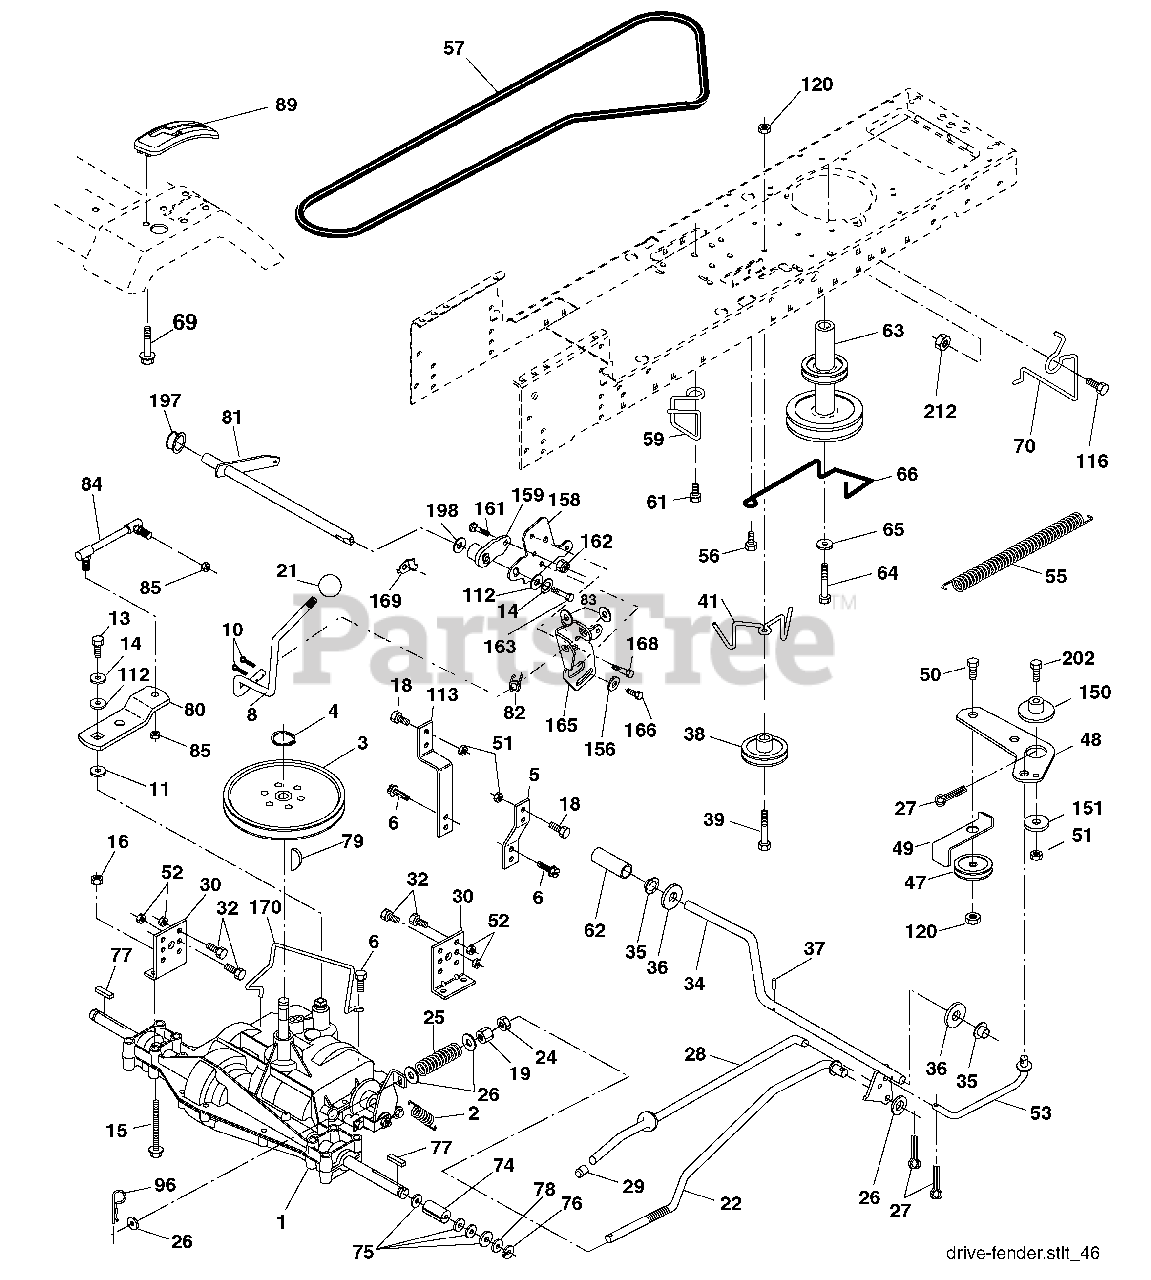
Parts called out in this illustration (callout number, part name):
2	Spring Return Brake T/a Zinc
3	Pulley Transaxle 18" tires
4	Ring Retainer # 5100-62
5	Strap Torque 30 Degrees
6	Screw 5/16-18 x 3/4
8	Rod Shift Fender Adjust Lt
10	Pin Cotter 1/8 x 1 Cad
11	Washer Plate Shf 388 Sq Hole
13	Bolt 1/4-28 unf Gr. 8 W/Patch
14	Washer Lock Hvy Helical
15	Bolt Hex FLGHD 5/16-18 Gr. 5
16	Nut Lock Hex w/ins 5/16-18
18	Bolt, Fin Hex 3/8-16 unc x 1 Gr. 5
19	Nut Lock 3/8-16 unc
21	Knob
22	Rod Brake Blk Zinc 26 840
24	Nut Hex Jam 3/8-16 unc
25	Spring Rod Brake 2 00 Zinc
26	Washer 13/32 x 13/16 x 16 Ga.
27	Pin Cotter 1/8 x 3/4 Cad
28	Rod Brake Parking LT/YT
29	Cap Brake Parking
30	Bracket Mtg Transaxle
32	Bolt Hex Hd 5/16-18 unc x 3/4
34	Shaft Asm Pedal Foot
35	Bearing Nylon Blk 629 Id
36	Washer 21/32 x 1 x 16 Ga.
37	Pin Roll 3/16 x 1"
38	Pulley Composite Flat
39	Bolt RDHD 3/8-16 unc x 2-3/4 Gr.
41	Keeper Belt Flat Idler
47	Pulley Idler V Groove Plastic
48	Bellcrank Asm
49	Retainer Belt Style Spring
50	Bolt Carr. Sh. 3/8-16 x 1-1/2 Gr. 5
51	Nut Crownlock 3/8-16 unc
52	Nut Crownlock 5/16-18 unc
53	Link Clutch
55	Spring Return Clutch 6 75
56	Screw 3/8-16 x 1-1/4
57	V-Belt Ground Drive 95 30
59	Keeper Belt Span Ctr
61	Screw 3/8-16 x .875
62	Cover Pedal Blk Round
63	Engine Pulley
64	Bolt Hex
65	Washer Lock Hvy Hlcl Spr 7/16
66	Keeper Belt Engine Foolproof
69	Screw Hex wsh HiLo 1/4 x 1/2 unc
70	Guide Belt Mower Drive RH
74	Spacer Axle
75	Washer 25/32 x 1 1/4 x 16 Ga.
76	E-ring #5133-75
77	Key Square 2 0 x 1845/ 1865
78	Washer 25/32 x 1-5/8 x 16 Ga.
79	Key Woodruff #9 3/16 x 3/4
80	Arm Shift
81	Shaft Asm Cross Tapered PMST/20
82	Spring Torsion T/a
83	Washer 17/32 x 3/4 x 16 Ga.
84	Link Transaxle
85	Nut Lock Center 1/4 - 28 FNTHD
89	Console Shift STLT
96	Retainer Spring 1"
112	Washer 9/32 x 3/4 x 10 Ga.
113	Strap Torque LT
116	Bolt Rdhd Sq Neck 3/8-16 x 1
120	Nut Lock Flg. 3/8-16 unc
150	Spacer Retainer
151	Washer 13/32 x 2 x 10
156	Washer Srrted 5/16ID x 1.125
158	Bracket Shift Mount
159	Hub Tapered Flange Shift Lt
161	Bolt Rdhd Sqnk 1/4-20 x 3/4
162	Nut Crownlock 1/4-20 unc
163	Bolt Hex Fin 1/4-20 unc x 1 Gr. 5
165	Bracket Pivot Lever
166	Screw 5/16-18 x 5/8
168	Bolt Shoulder 5/16-18 x .561
169	Plate Fastening
170	Keeper Belt Transaxle Gear
197	Nyliner Snap-In
198	Washer Nyliner
202	Bolt RdHd 3/8-16 unc x 1-3/4 Gr. 5
212	Nut Hexfl ange Lock
